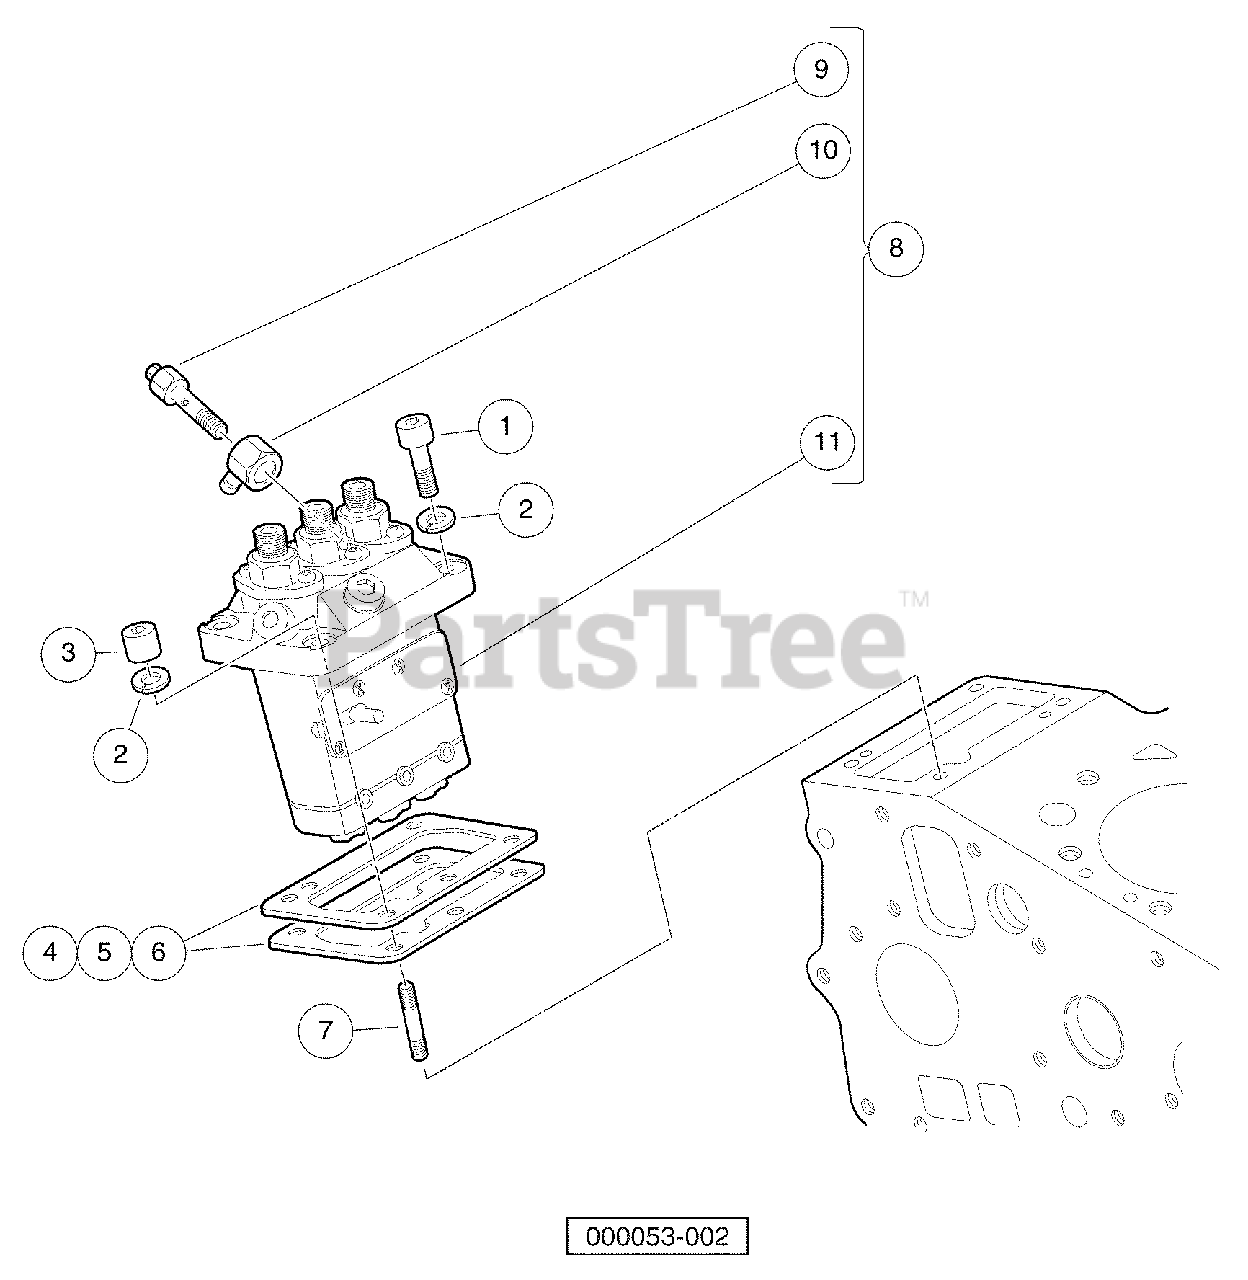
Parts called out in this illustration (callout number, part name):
1	Bolt, Hex-Head, M5 X 0.75 X
2	Washer, Spring, M6, D722
3	Nut, Special.
4	Shim, Injection Pump, 0.20 mm
5	Shim, Injection Pump, 0.25 mm
6	Shim, Injection Pump, 0.30 mm
7	Stud, M5 X 25.
8	Assembly, Fuel Injection Pump
9	Screw, Hollow, D722, Inj Pump
10	Joint, Eye
11	Pump, Injection
